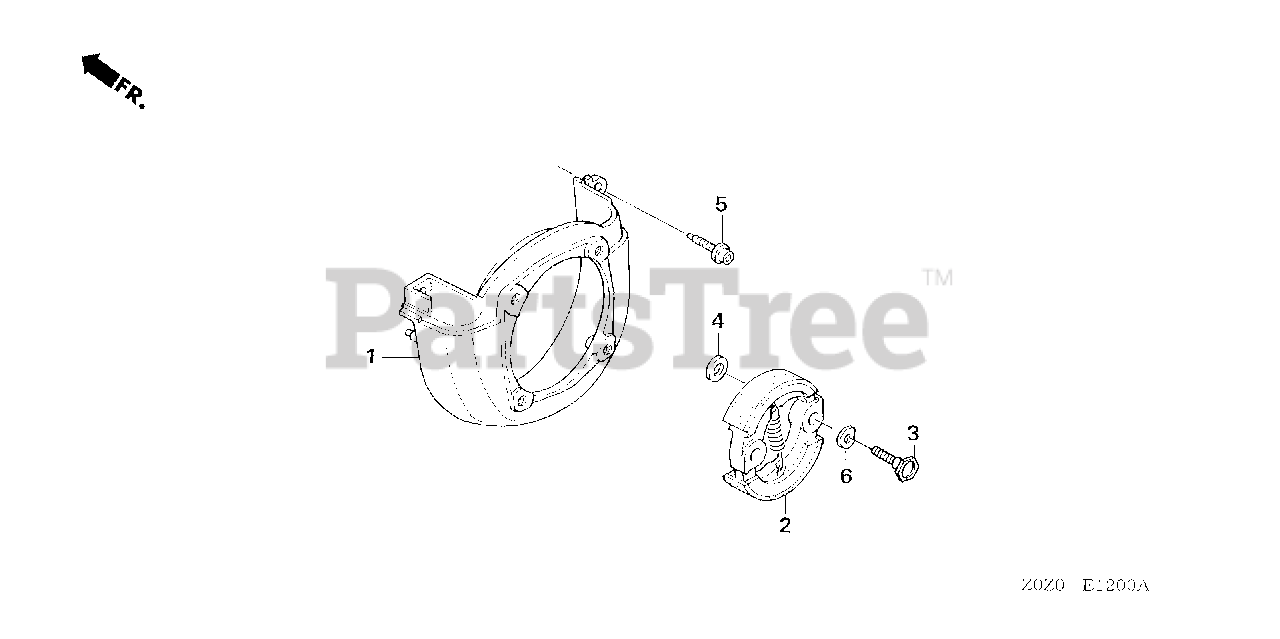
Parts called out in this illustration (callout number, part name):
1	COVER, FAN
2	CLUTCH ASSY.
3	BOLT, CLUTCH (8MM)
4	WASHER, CLUTCH (8X17)
5	BOLT, SOCKET (5X20)
